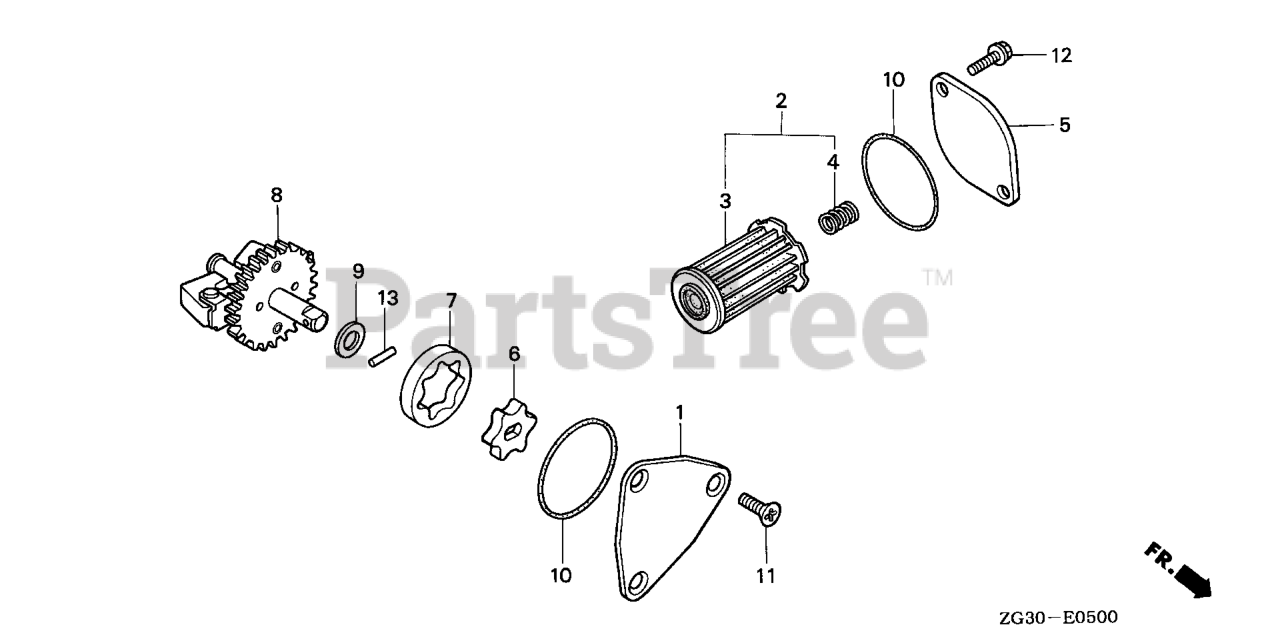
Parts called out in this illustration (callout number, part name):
1	COVER, OIL PUMP
2	STRAINER, OIL
3	STRAINER, OIL
4	SPRING, OIL STRAINER
5	COVER, OIL STRAINER
6	ROTOR, OIL PUMP (INNER)
7	ROTOR, OIL PUMP (OUTER)
8	WEIGHT, GOVERNOR
9	WASHER (10.1MM)
10	O-RING (42.2X2.4)
11	SCREW, FLAT (6X16)
12	BOLT, FLANGE (6X16) Use from Engine SN 2056820.
13	ROLLER (3X13.4)
